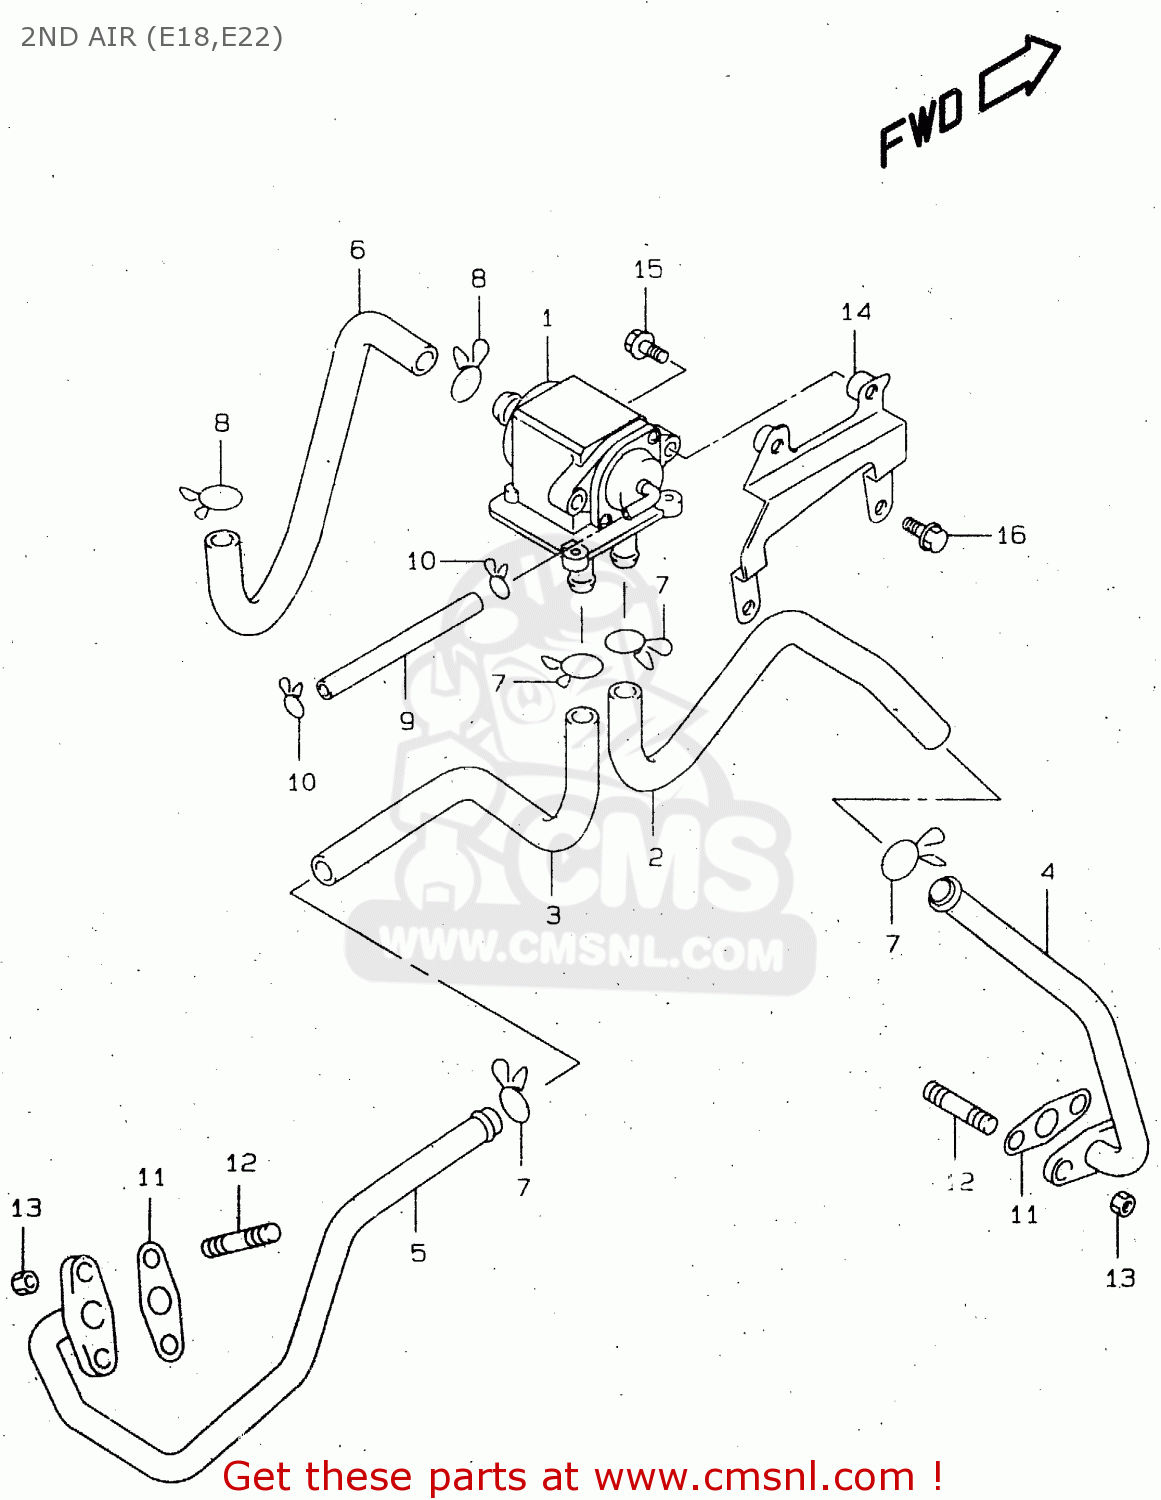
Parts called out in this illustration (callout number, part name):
1	VALVE ASSEMBLY,SECOND AIR
2	HOSE,2ND AIR VALVE FR
3	HOSE,2ND AIR VALVE RR
4	PIPE COMP,SECOND AIR,FRONT
5	PIPE,2ND AIR RR
6	HOSE,2ND AIR CLEANER
7	CLIP
8	CLIP
9	HOSE(4X7X600)
10	CLIP
11	GASKET,SECOND AIR PIPE (N (NAS)
12	STUD BOLT
13	NUT
14	BRACKET,2ND AIR VALVE
15	BOLT,OIL FILLE
16	BOLT
